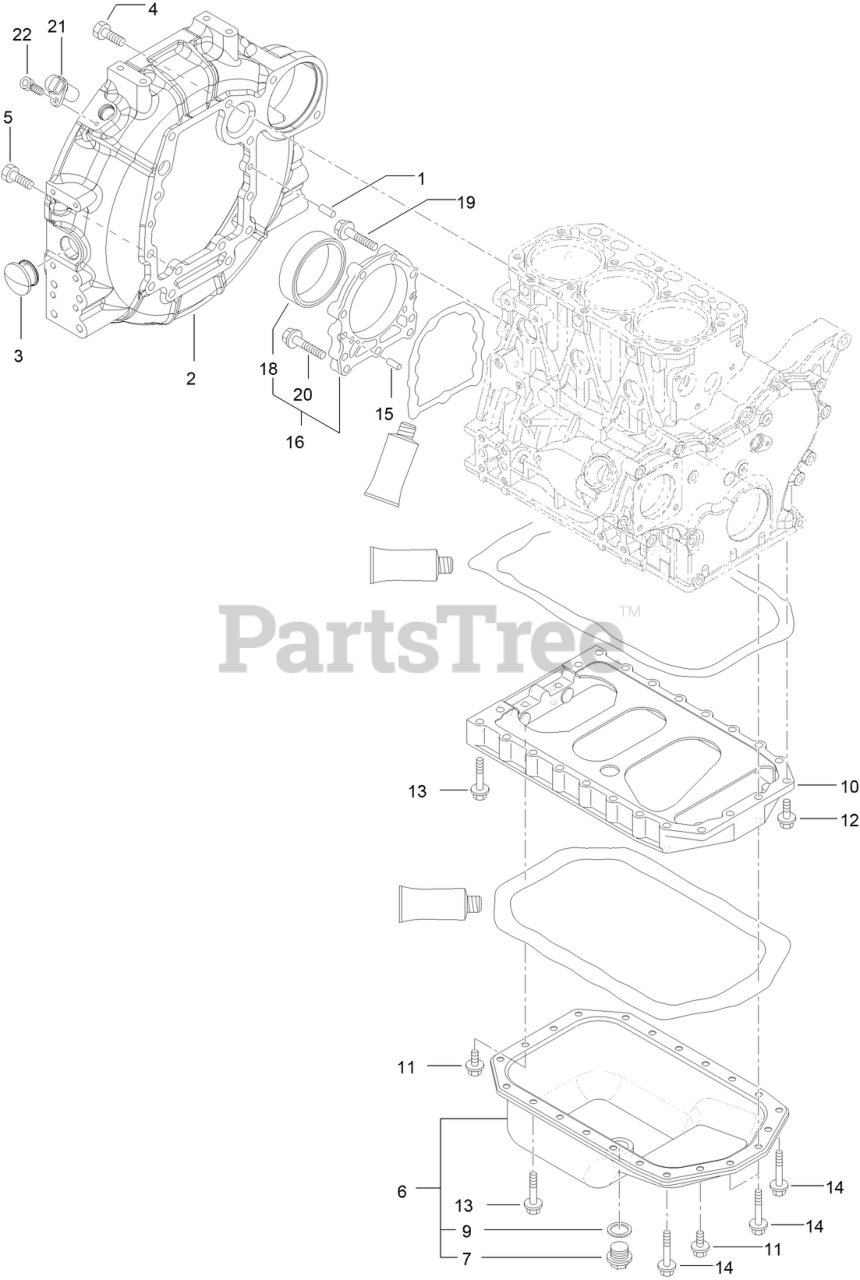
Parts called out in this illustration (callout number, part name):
2	HOUSING-FLYWHEEL
6	OIL PAN ASM
7	PLUG-DRAIN
9	WASHER-SEAL
10	SPACER
11	BOLT
16	CASE ASM
18	SEAL-OIL
21	SENSOR-REV, FLYWHEEL
